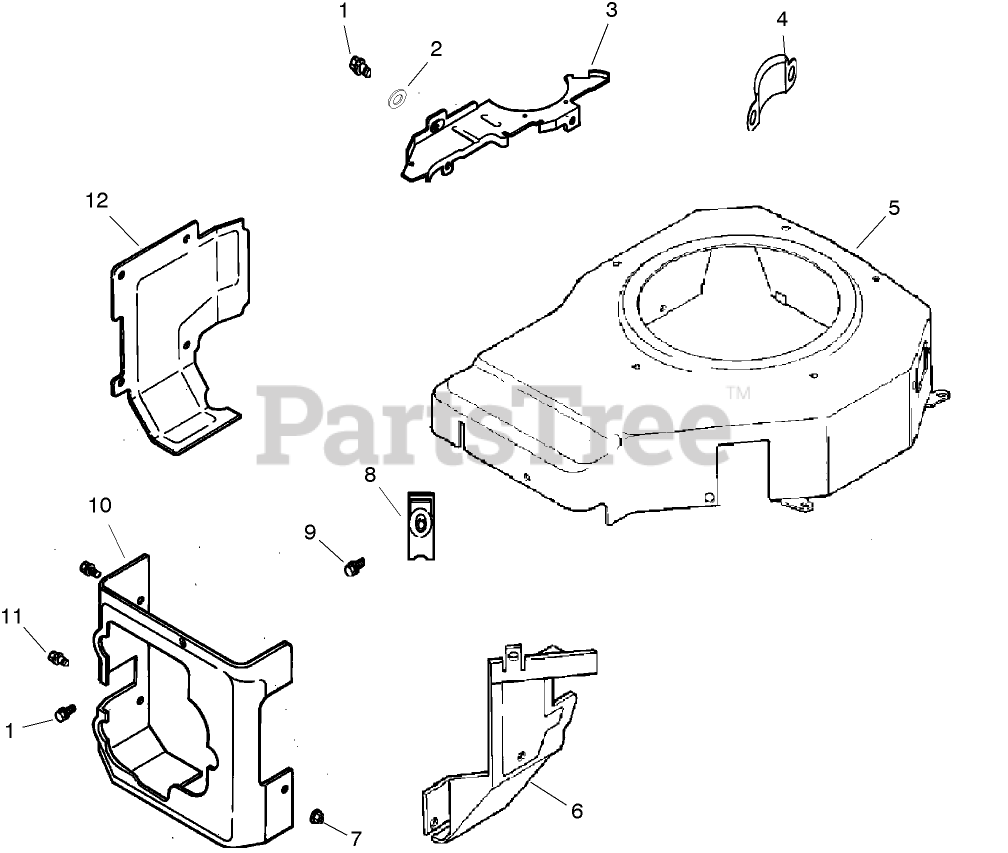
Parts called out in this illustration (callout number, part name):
1	SCREW-HHFTF (M5X.80X10)
2	Washer-plain (1/4)
3	Plate-Housing, Blower
4	Cover-Pinion
5	Housing-Blower
6	Baffle (Intake Side)
7	Nut-HF (M5x0.8)
8	Clip-Mounting
9	SCREW-FLANGE, THREAD FORMING (M6X1.0X16)
10	Baffle (Cylinder Head)
11	Screw-Washer, Captive (M5x0.8x20)
12	Baffle-Cylinder
